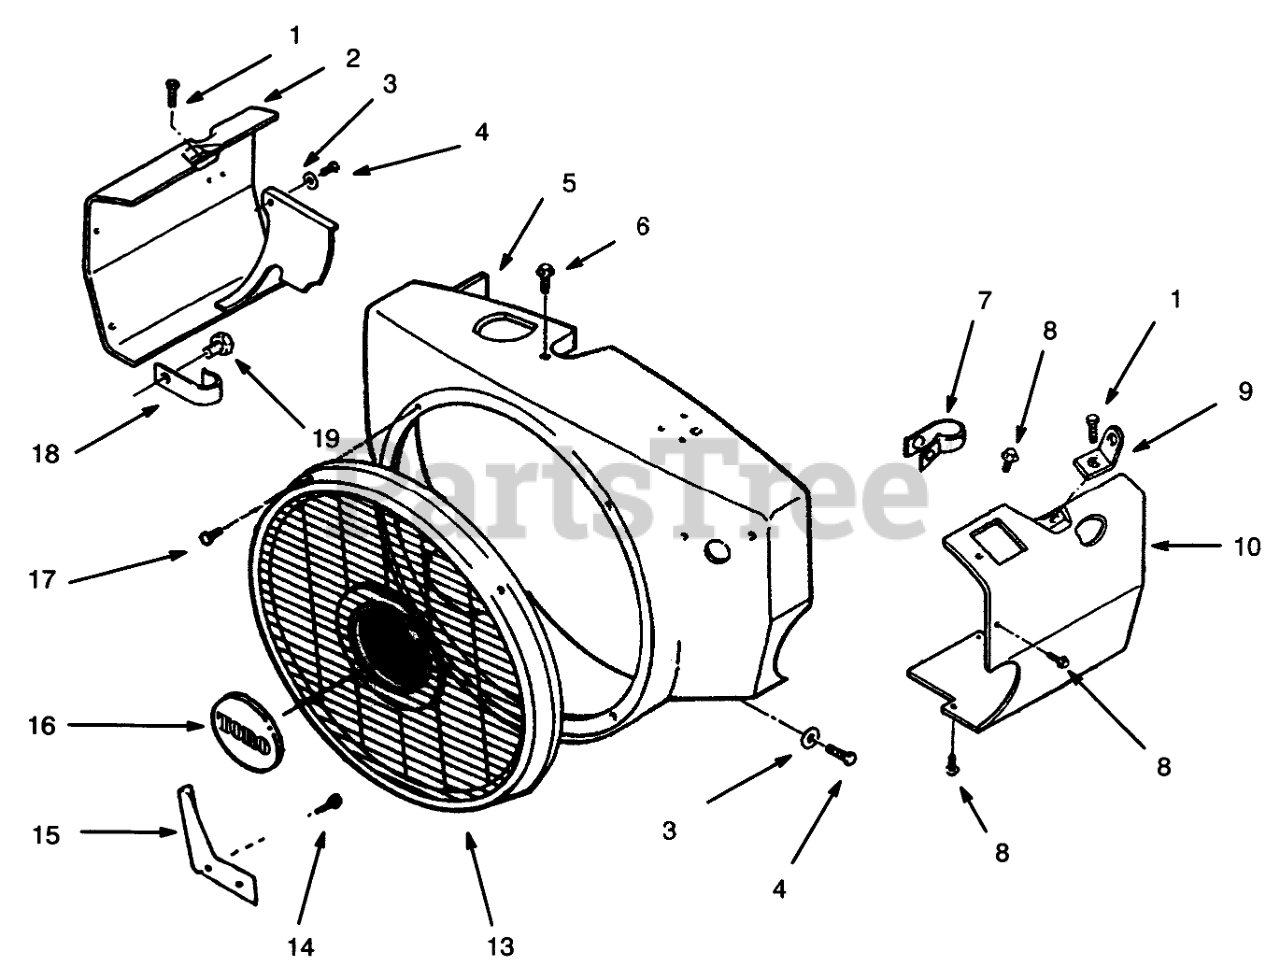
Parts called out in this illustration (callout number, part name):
1	SCREW-HWH
2	LH AIR CYLINDER HSG
3	SCREW-HH
4	WASHER-FLAT
5	HOUSING
6	HEX HD CAPSCREW
7	Clamp
8	SCREW-HWH
9	BRACKET-LIFTING
10	RH AIR CYLINDER HSG
13	GUARD-STATIONARY
14	SCREW - THREAD CUTTING
15	BRACKET
16	NAME-PLATE TORO LOGO
17	SCREW-PAN HEAD
18	Clip
19	SCREW-HWH
